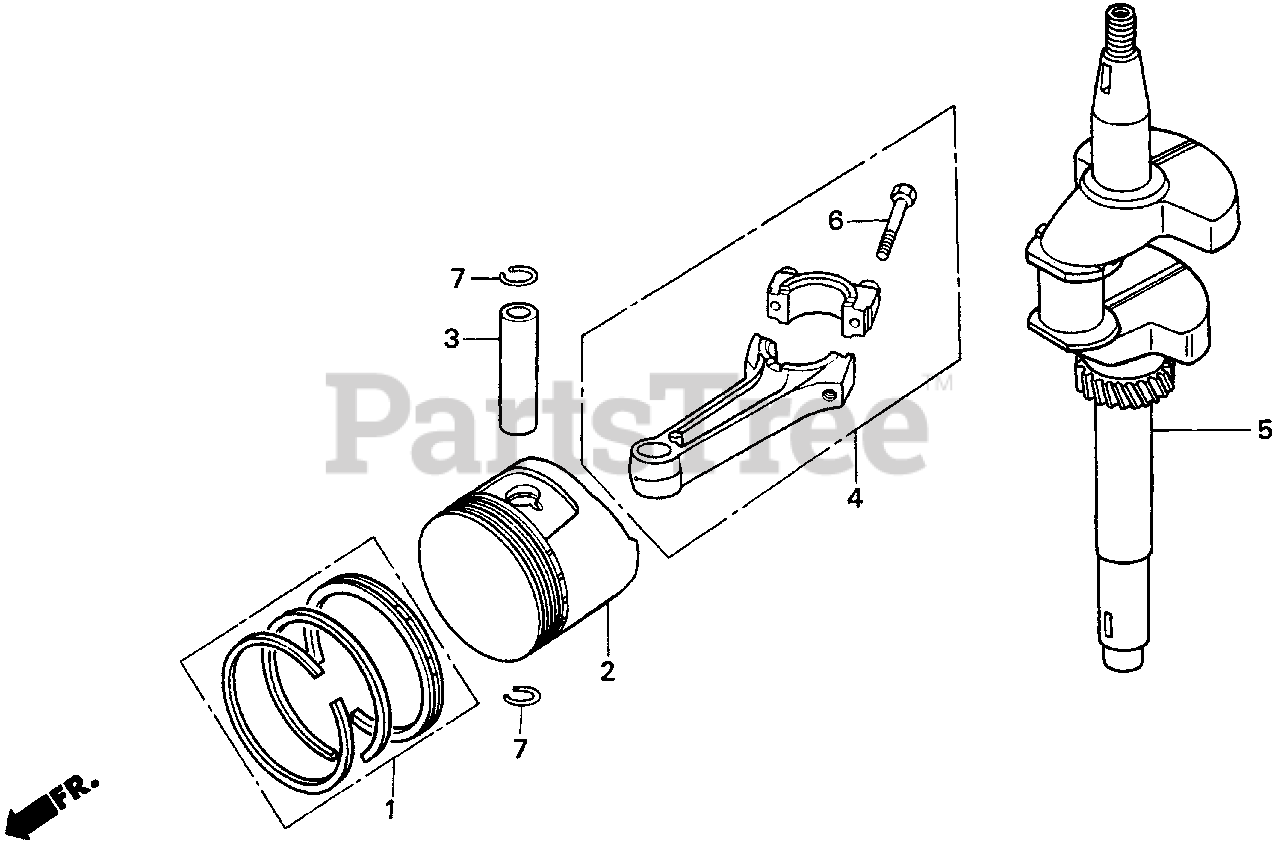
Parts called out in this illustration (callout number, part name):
1	RING SET, PISTON (STD) (TEIKOKU)
1	RING SET, PISTON (STD) (NIPPON)
1	RING SET, PISTON (0.25) (TEIKOKU)
1	RING SET, PISTON (OVER SIZE) (0.25) (TEIKOKU) Use up to Engine SN 4733210.
1	RING SET, PISTON (0.50) (TEIKOKU)
1	RING SET, PISTON (0.50) (NIPPON)
1	RING SET, PISTON (OVER SIZE) (0.50) (TEIKOKU) Use up to Engine SN 4733210.
1	RING SET, PISTON (0.75) (TEIKOKU)
1	RING SET, PISTON (0.75) (NIPPON)
1	RING SET, PISTON (OVER SIZE) (0.75) (TEIKOKU) Use up to Engine SN 4733210.
1	RING SET, PISTON (0.75) (NIPPON) (NOT AVAILABLE)
2	PISTON (STD)
2	PISTON (0.25)
2	PISTON (OS 0.50)
2	PISTON (0.75)
3	PIN, PISTON
4	ROD ASSY., CONNECTING
4	ROD ASSY., CONNECTING (0.25 LOWER SIZE) (NOT AVAILABLE)
5	CRANKSHAFT
6	BOLT, CONNECTING ROD
7	CLIP, PISTON PIN (18MM)
